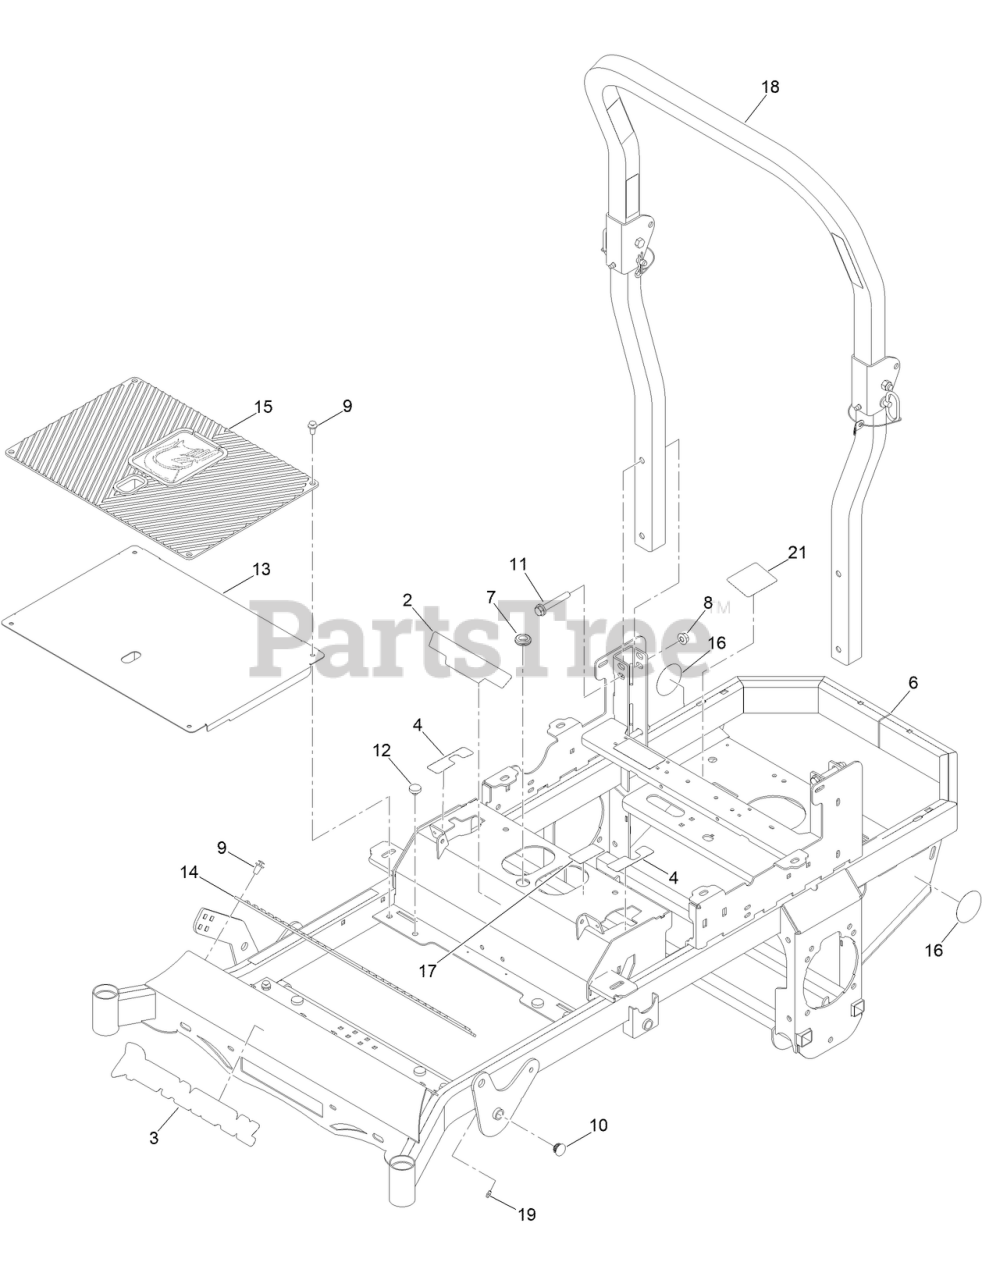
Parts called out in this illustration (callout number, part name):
2	DECAL- RZ HD GT TRAC BLACKOUT MODEL
3	DECAL- SPARTAN BLACKOUT LOGO
4	DECAL-MOTION CONTROL
6	ASM FRAME W/DECALS
7	GROMMET-RUBBER
8	1/2-13 HEX STOVER LOCKNUT GR C ZINC
9	8MM PUSH TYPE RETAINER NYLON BLACK
10	1IN ROUND TUBE PLUG
12	PUSH-IN RUBBER BUMPER MWR FLOOR
13	RZ FLOORBOARD PAINTED BLACK
14	MWR RUBBER FOOT REST MAT
15	MWR LOGO FLOOR MAT
16	MWR PARKER PUMP DECAL
17	DECAL-WEIGHT, SEAT
18	MWR FOLD DOWN ROPS
18	SPARTAN FOLDING ROPS BOXED
19	1/4 DRIVE TYPE STRAIGHT GREASE FITTNG ZC
21	DECAL-PUMP BELT ROUTING-PARKER
